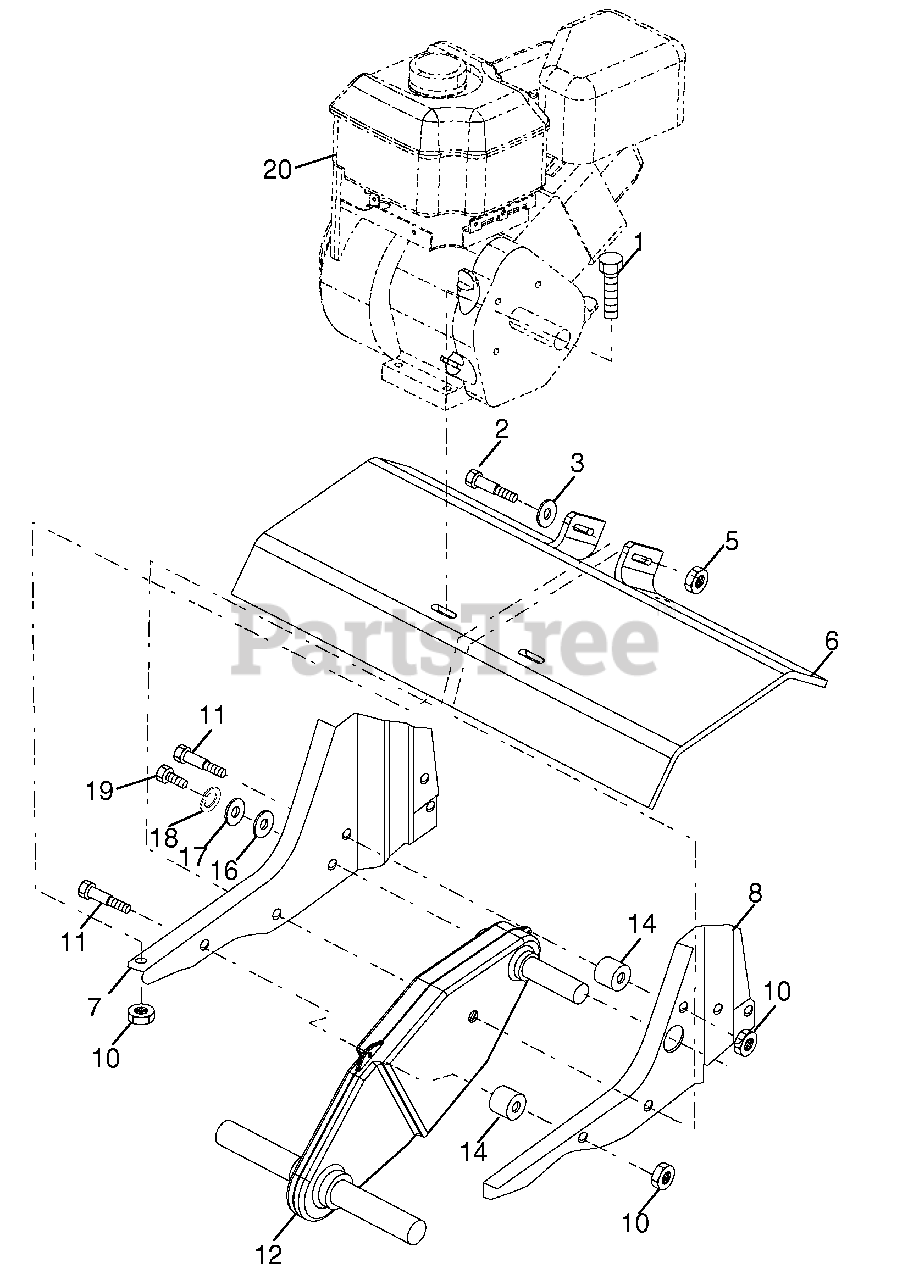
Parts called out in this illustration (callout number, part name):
1	Bolt, Hex Head, Gr. 25/16-18 x 1-1/2
2	Bolt, Hex Head, 3/8-16 x 3-1/4
3	Washer, 3/32 x 13/16 x 11
5	Nut, Hex, Flangelock 3/8-16
6	Shield, Tine
7	Bracket, Engine, R.H.
8	Bracket, Engine, L.H.
10	Nut, Hex, Flangelock
11	Bolt, Shoulder
12	Transmission
14	Spacer, Split
16	Washer, 9/32 x 7/8 x 12 Ga.
17	Washer, 9/32 x 1-1/4 x 16 Ga.
18	Washer, Lock 1/4
19	Bolt, Hex Head, Gr. 51/4-28 x 3/4
